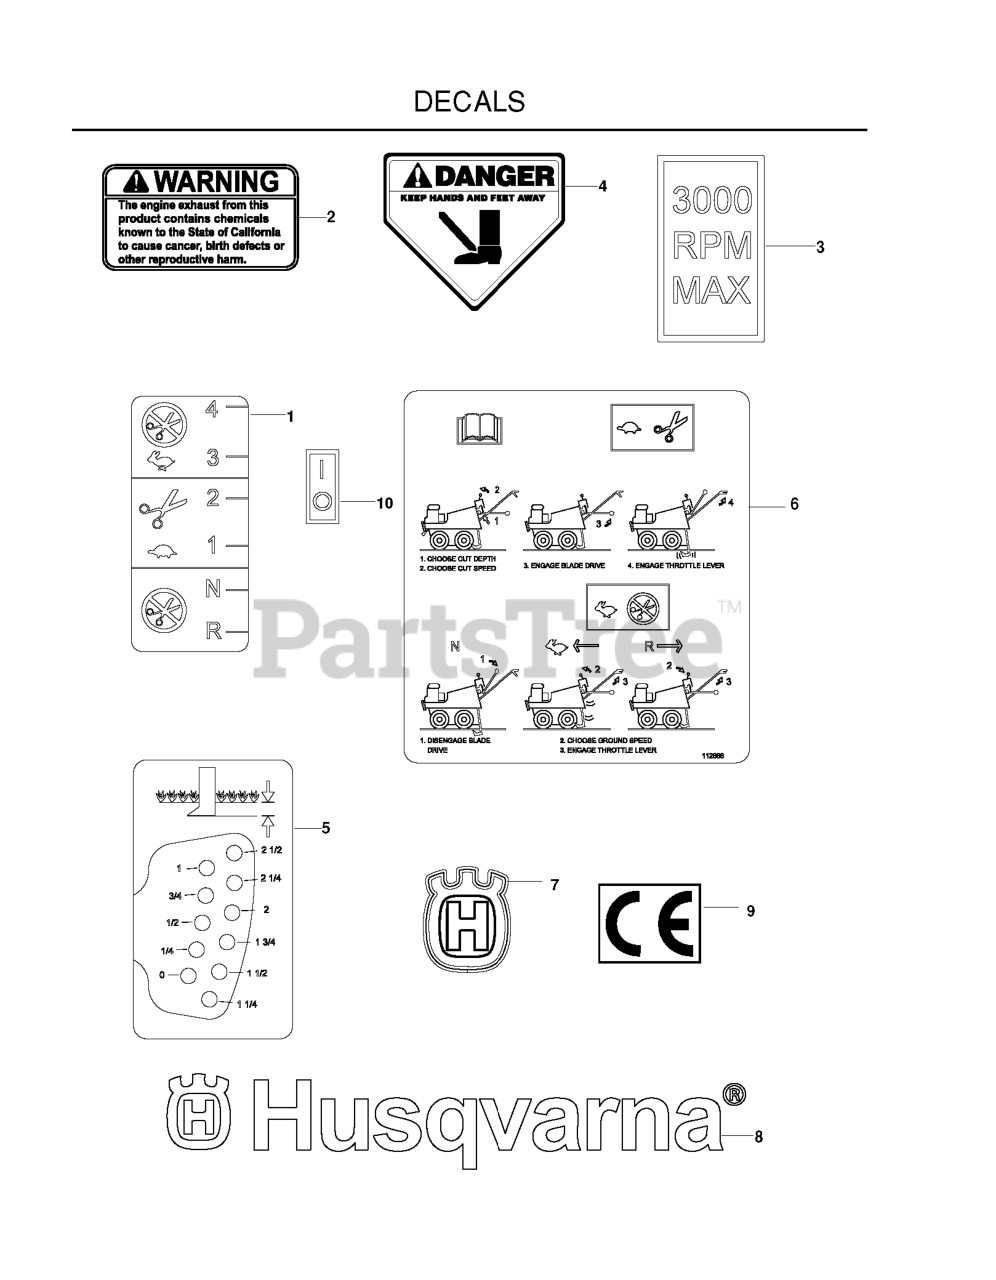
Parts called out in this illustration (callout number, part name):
1	DECAL, SHIFT
2	DECAL, PROP. 65
3	DECAL, 3000 MAX RPM, HUSQ
4	DECAL, FOOT DANGER
5	DECAL, DEPTH OF CUT
6	DECAL, OPERATION
7	DECAL.AUGER.HUSQ.CROWN.SNOW
8	RP.DECAL.BADGE.170MM.TEXTLOGO
10	DECAL, ON/OFF
